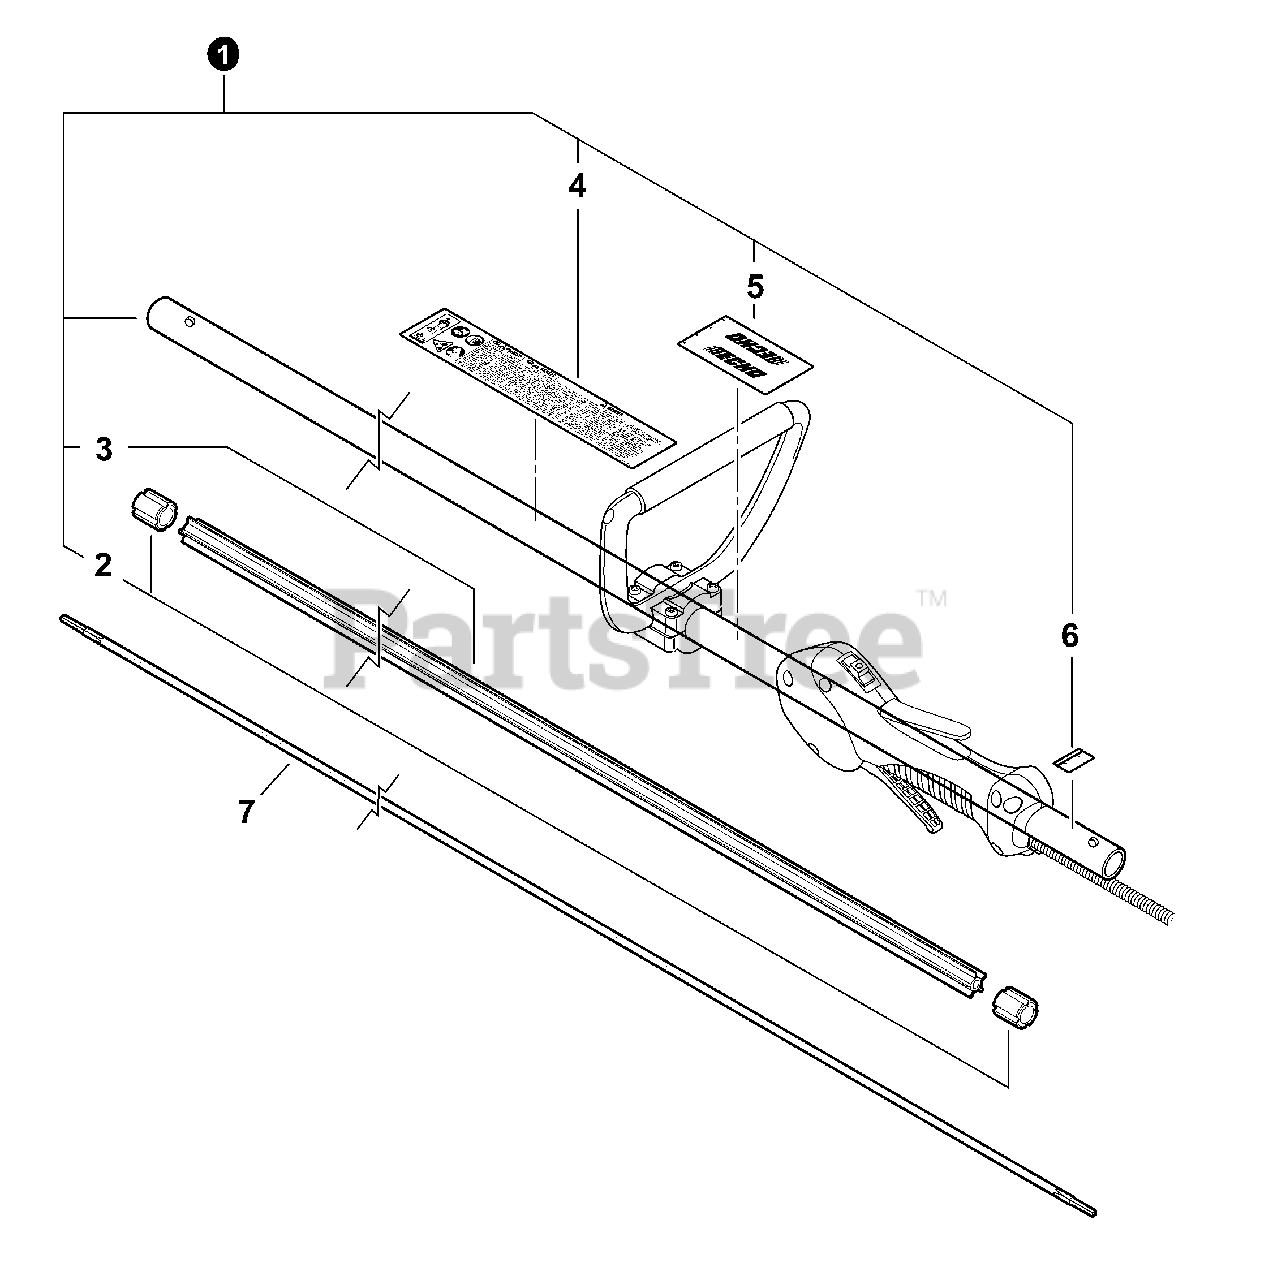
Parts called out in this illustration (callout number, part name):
1	MAIN PIPE ASSY
3	LINER, FLEXIBLE 21.6×1420
4	LABEL, CAUTION
5	LABEL, HANDLE LOCATION
6	LABEL - ALIGNMENT
7	DRIVESHAFT - FLEXIBLE L= 1522
